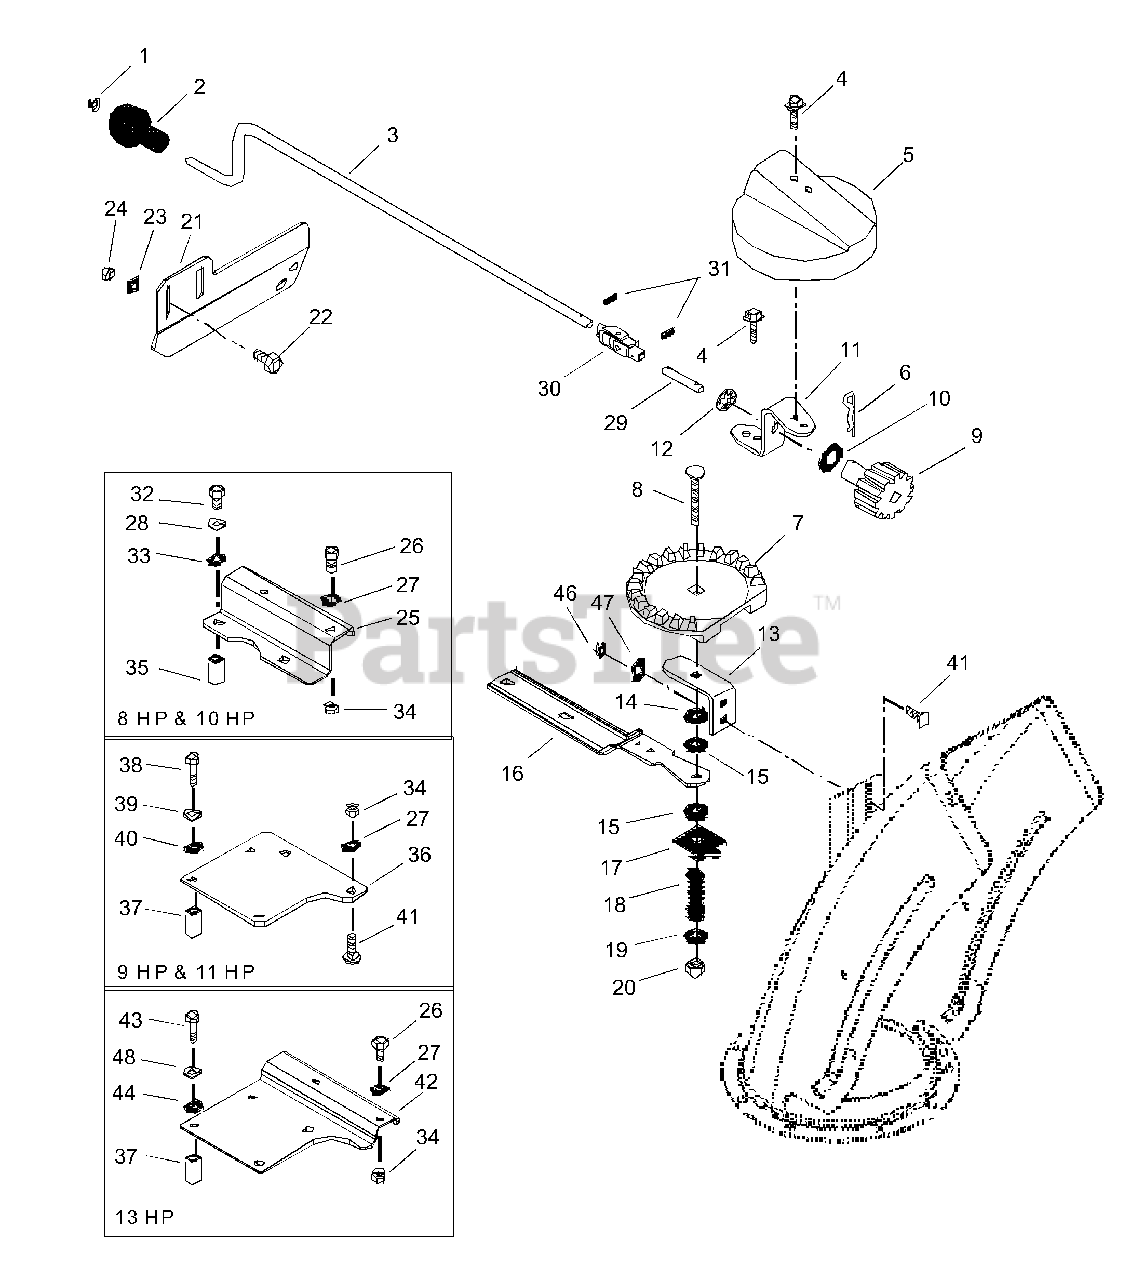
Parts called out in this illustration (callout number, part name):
1	CAP, 3/8 ROD YWZC
3	CRANK, CHUTE
4	@SCR-TAP .25-20X.50 HWH TR YWZ
5	GEAR COVER
6	PIN-HAIR INT .08X.38X1.42 YWZC
7	CHUTE GEAR
8	@BLT-RDHDSQNK .38-16X2.50 G5YZ
9	PINION GEAR W/BRACKET
10	WSHR-FL-STL .630X1.005X.062 YZ
11	BRACKET-GEAR
12	PUSHNUT .625
13	GEAR STRAP
14	WSHR-FL-STL .380X1.50X.062 YWZ
15	FRICTION WASHER
16	BRACKET, CHUTE SUPPORT
17	FRICTION PLATE
18	SG-COMP .187X.56X1.62
19	@WSHR-FL-STL.406X.812X.065 YWZ
20	@NUT-LK-CTR .38-16 YWZC
21	BRACKET, CHUTE CRANK
22	@BLT-HEX .25-20X.50 GR5 YWZC
23	@WSHR-FL-STL.312X.734X.065 YWZ
24	@NUT-LK-CTR .25-20 YWZC
25	BRACKET, ENGINE-8&10
26	BLT-HEX .31-18X.75 GR5 BLZC
27	WSHR-FL-STL .313X.74X.065 BLZC
28	@WSHR-LK .31X.078 REG YWZC
29	PIN, CONNECTOR
30	UNIVERSAL JOINT ASS'Y
31	PIN-ROLL .125X.75
32	@BLT-HEX .31-18X1.25 GR5 YWZC
33	@WSHR-FL-STL.344X.688X.065YWZC
34	NUT-LK-CENTER .31-18 BLZC
35	SPACER .322X.626X.50
36	BRACKET, ENGINE
37	SPACER, TUBE
38	@BLT-HEX .25-20X.75 GR5 YWZC
39	@WSHR-LK .25X.062 REG YWZC
40	@WSHR-FL-STL.281X.62X.065 YWZC
41	@BLT-RDHDSQNK .25-20X.75 G5YZ
42	BRACKET, ENGINE-13 HP
43	@BLT-HEX .25-20X.75 GR5 YWZC
44	@WSHR-FL-STL.281X.62X.065 YWZC
45	BLT-RDHDSQNK .31-18X.75 PL BL
46	@NUT-HEX .25-20 YWZC
47	@WSHR-LK .25X.062 REG YWZC
48	@WSHR-LK .25X.062 REG YWZC
